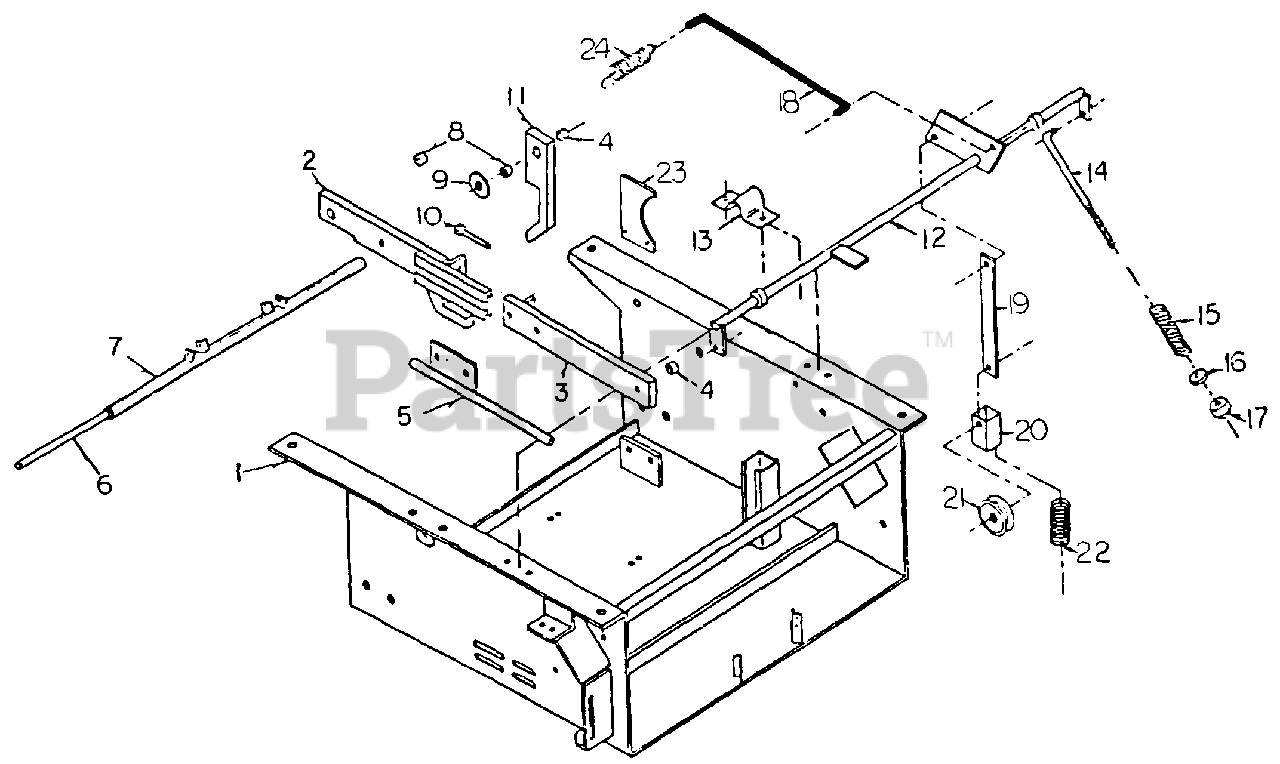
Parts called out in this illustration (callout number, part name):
1	Base
2	Deck Lift Arm, Front RH
3	Deck Lift Arm, Back
4	Bushing, Short
6	Cross Bar Pin
8	Bushing, Long
9	Body Mount Washer
10	Tap Bolt, 3/8-16 x 3", GR5
11	Forward Nose Down Lock
12	Brake Clutch Cross Rod
13	Bearing, Brake Cross Rod
15	Caliper Spring
16	Flatwasher, 1/4"
17	Elastic Stop Nut, 1/4-20
18	Brake Pedal Rod
19	Cross Rod to Idler Pulley Linkage
20	Spring Loaded Idler Mount
21	Idler Pulley
24	Brake Pedal Spring
